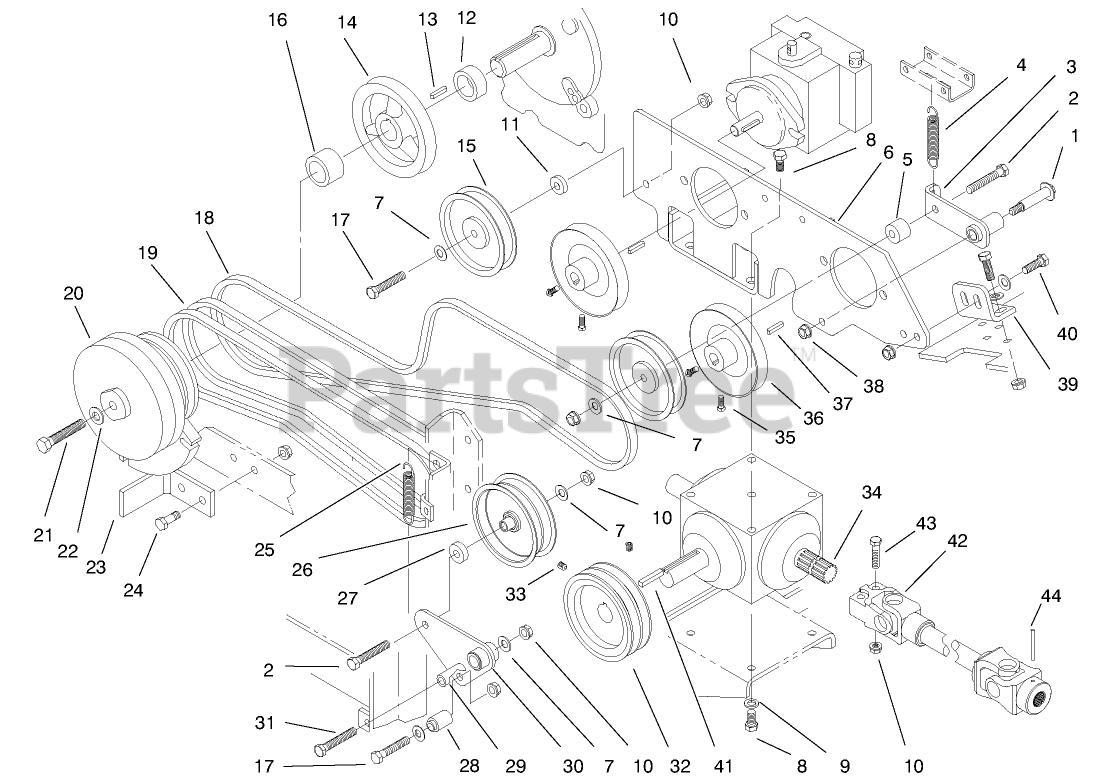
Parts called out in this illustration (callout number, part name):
1	BOLT-WHEEL
2	SCREW-HH
3	IDLER ARM ASM
4	SPRING-EXTENSION
5	SPACER-ARM, IDLER
6	PUMP MOUNT ASM
7	WASHER-FLAT
8	SCREW-HHF
10	NUT-LOCK, NI
11	Washer
12	SPACER-SHAFT, ENGINE
14	PULLEY-ENGINE
15	PULLEY-IDLER
16	SPACER-SHAFT, ENGINE
17	SCREW-HH
18	V-BELT
19	BELT - PTO (SET)
20	Clutch ASM
21	SCREW-HH
22	WASHER-FLAT
23	STOP-CLUTCH
24	SCREW-HH
25	SPRING-EXTENSION
26	PULLEY-IDLER
27	SPACER-IDLER
28	SPACER - SPRING
29	SPACER
30	IDLER ARM ASM
31	Screw-Hhcs
32	PULLEY-CLUTCH
33	SCREW-HSH
34	Gearbox-PTO Drive
35	SCREW-SET
36	PULLEY-PUMP, TRACTION
37	KEY-PUMP
38	NUT-LOCK
39	MOUNT-PLATE, PUMP
40	SCREW-HHF
41	KEY-SQUARE
42	SHAFT-DRIVE
43	SCREW-HH
44	PIN-SPRING
